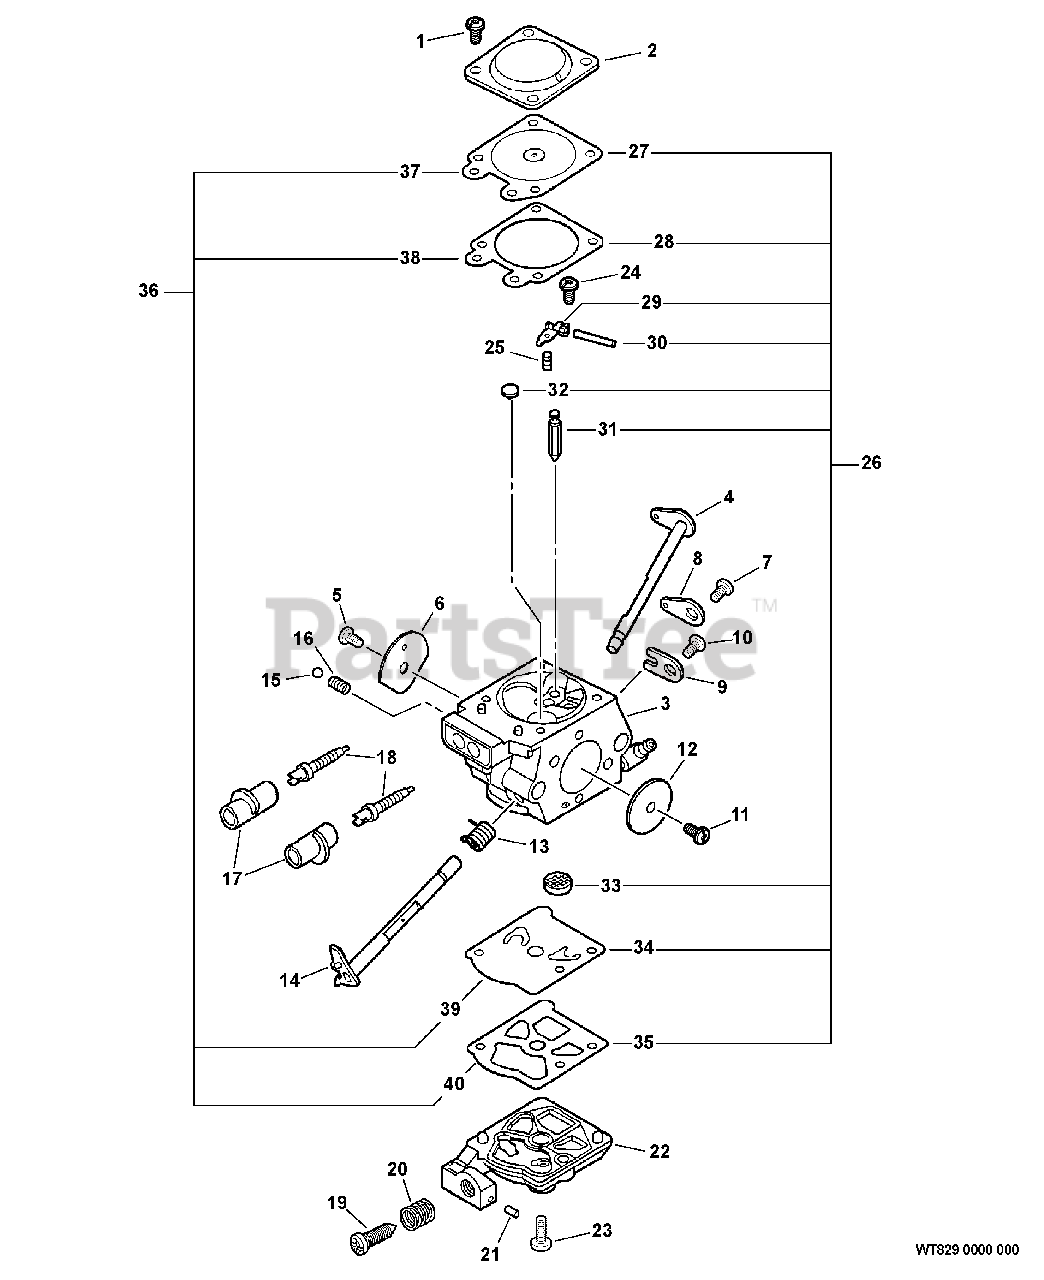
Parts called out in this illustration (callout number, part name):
2	COVER, METERING DIAPHRAGM
3	BODY, CARBURETOR
4	SHAFT, CHOKE
6	VALVE, CHOKE
8	LEVER, THROTTLE
9	CLIP, THROTTLE SHAFT
12	VALVE, THROTTLE
13	SPRING, THROTTLE RETURN
14	SHAFT ASSY, THROTTLE
16	BALL, CHOKE FRICTION
17	CAP, LIMITER
18	NEEDLE, MIXTURE
19	SCREW, IDLE ADJUST
20	SPRING, IDLE ADJUST
21	PLUG, FRICTION
22	COVER, FUEL PUMP
24	SCREW, METERING LEVER PIN
25	SPRING, METERING LEVER
26	REPAIR KIT, CARBURETOR
27	DIAPHRAGM, METERING
28	GASKET, DIAPHRAGM
29	LEVER, METERING
30	PIN, METERING LEVER
31	VALVE, INLET NEEDLE
32	PLUG, WELCH
33	STRAINER
34	DIAPHRAGM, PUMP
35	GASKET, PUMP
36	GASKET / DIAPHRAGM KIT
37	DIAPHRAGM, METERING
38	GASKET, DIAPHRAGM
39	DIAPHRAGM, PUMP
40	GASKET, PUMP
